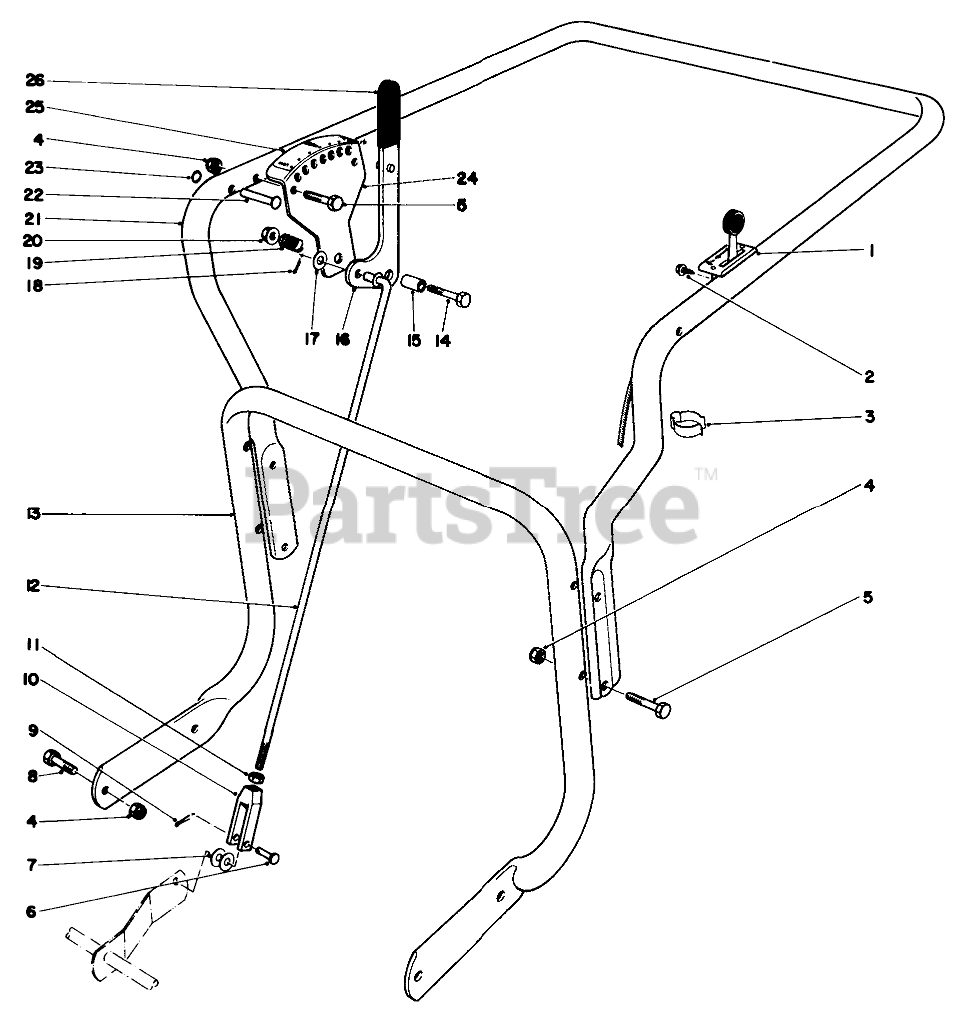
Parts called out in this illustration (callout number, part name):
1	Throttle Control
2	SCREW-HWHTF
3	BODEN CLIP
4	NUT-LOCK, NI
5	SCREW-HH
6	PIN-CLEVIS
7	WASHER-PLAIN
8	SCREW-HH
9	PIN-COTTER
10	Yoke
11	NUT-HJ
12	Connector Rod
13	HANDLE
14	SCREW-HH
15	SPACER
16	Adjustment Handle
17	WASHER-FLAT
18	PIN-COTTER
19	SPRING-COMPRESSION
20	NUT-HF
21	Handle
22	RIVET
23	RING-GRIP
24	Adjustment Bracket
25	HT ADJ DECAL
26	GRIP-HANDLE
